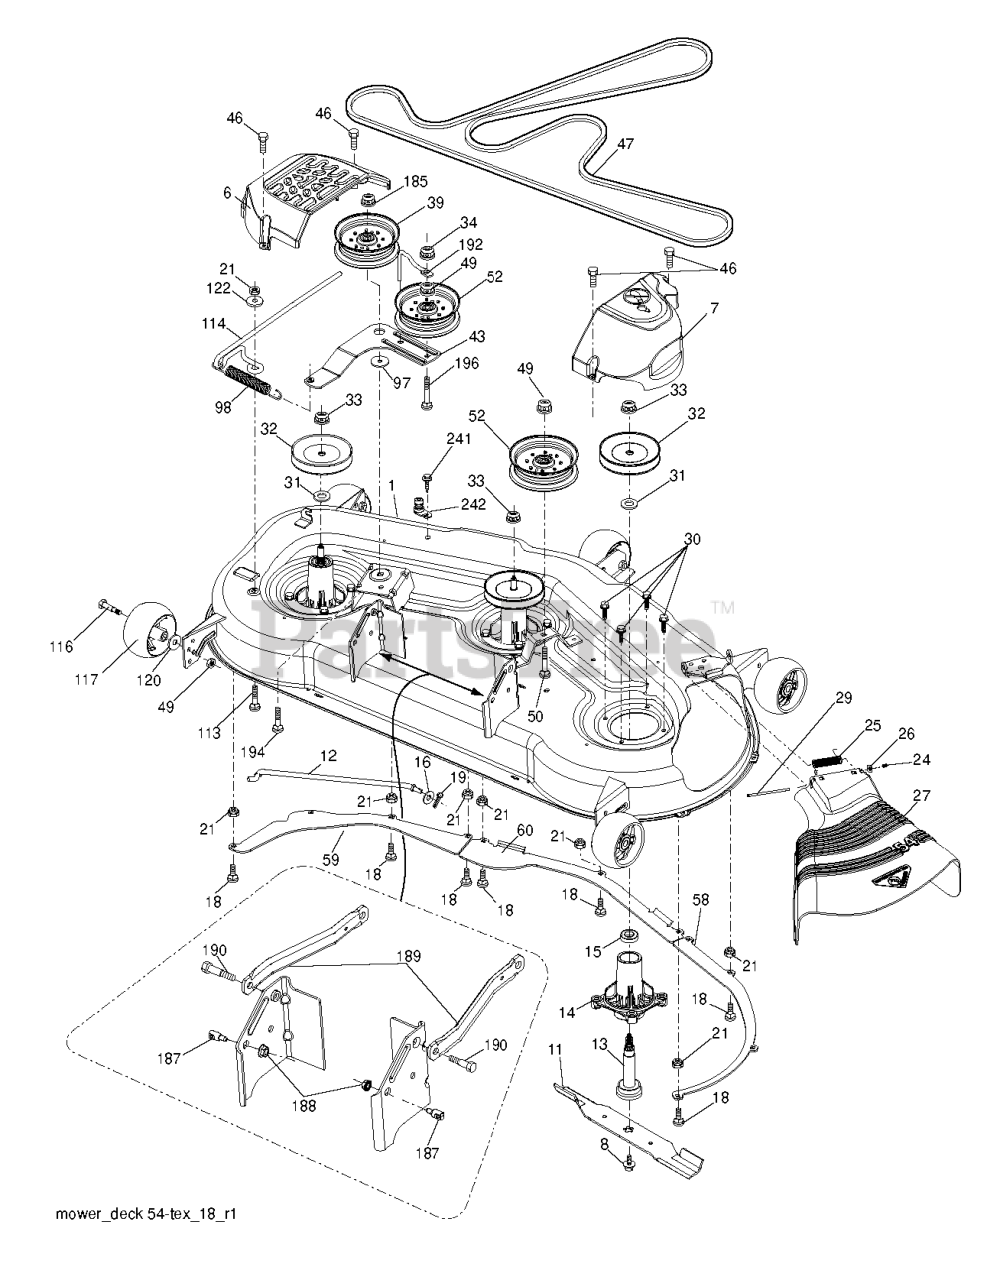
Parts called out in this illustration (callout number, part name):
1	DECK.WELDMENT.54"MS418
6	COVER.MANDREL.LH.54"20
7	COVER.MANDREL.RH.54.20
8	BOLT.WASHER.ASM.7/16-2
11	54" MULCH BLADE
11	BLADE.BAGGING.54"
12	ROD.ANTI.SWAY.48/54"K4
13	SHAFT ASM MANDREL
14	RP.HOUSING.MANDREL.4PT.
16	WASHER
18	BOLT
19	PIN.COTTER.5/16.BOW TI
21	LOCKNUT
24	CAP-SLEEVE LT
25	SPRING, TORSION
26	NUT PUSH M
27	DEFLECTOR
29	ROD.HINGE
30	SCREW, WASHER HEAD
31	WASHER.SPACER.MANDREL
32	PULLEY/MANDREL
33	NUT.FLANGE.LOCK.TOP
39	RB PULLEY.IDLER.4.50/HUB SPEC
46	SCREW.1/4-20X5/8
47	RP.BELT.DRIVE.54."2006
49	NUT LOCK FLG 3/8-16 UNC
52	PULLEY.IDLER.2006
58	BAFFLE.RIGHT.54"
59	BAFFLE.LEFT.54"
60	BAFFLE CENTER 54" MOWER
98	SPRING, DECK DRIVE
114	ROD TENSION RELIEF
116	BOLT.SHOULDER.3/8-16X3-5/8.
117	RP WHEEL. GUAGE RALLY
120	WASHER
122	BUSHING.RELIEF.TENSION
185	NUT.LOCK.FLANGE.7/16
187	STUD.FASTNER.W/ANTI-ROTATE
188	NUT LOCK HEX FLANGE 5/16-18
189	ARM.SUSPENSION.MOWER
190	BOLT.SHOULDER
192	KEEPER.BELT.IDLER.54"T
194	BOLT.CARR.SQNK.7/16
241	SCREW.TT.#10-32X.5.3/8.FLANGE
242	PORT.WASHOUT
